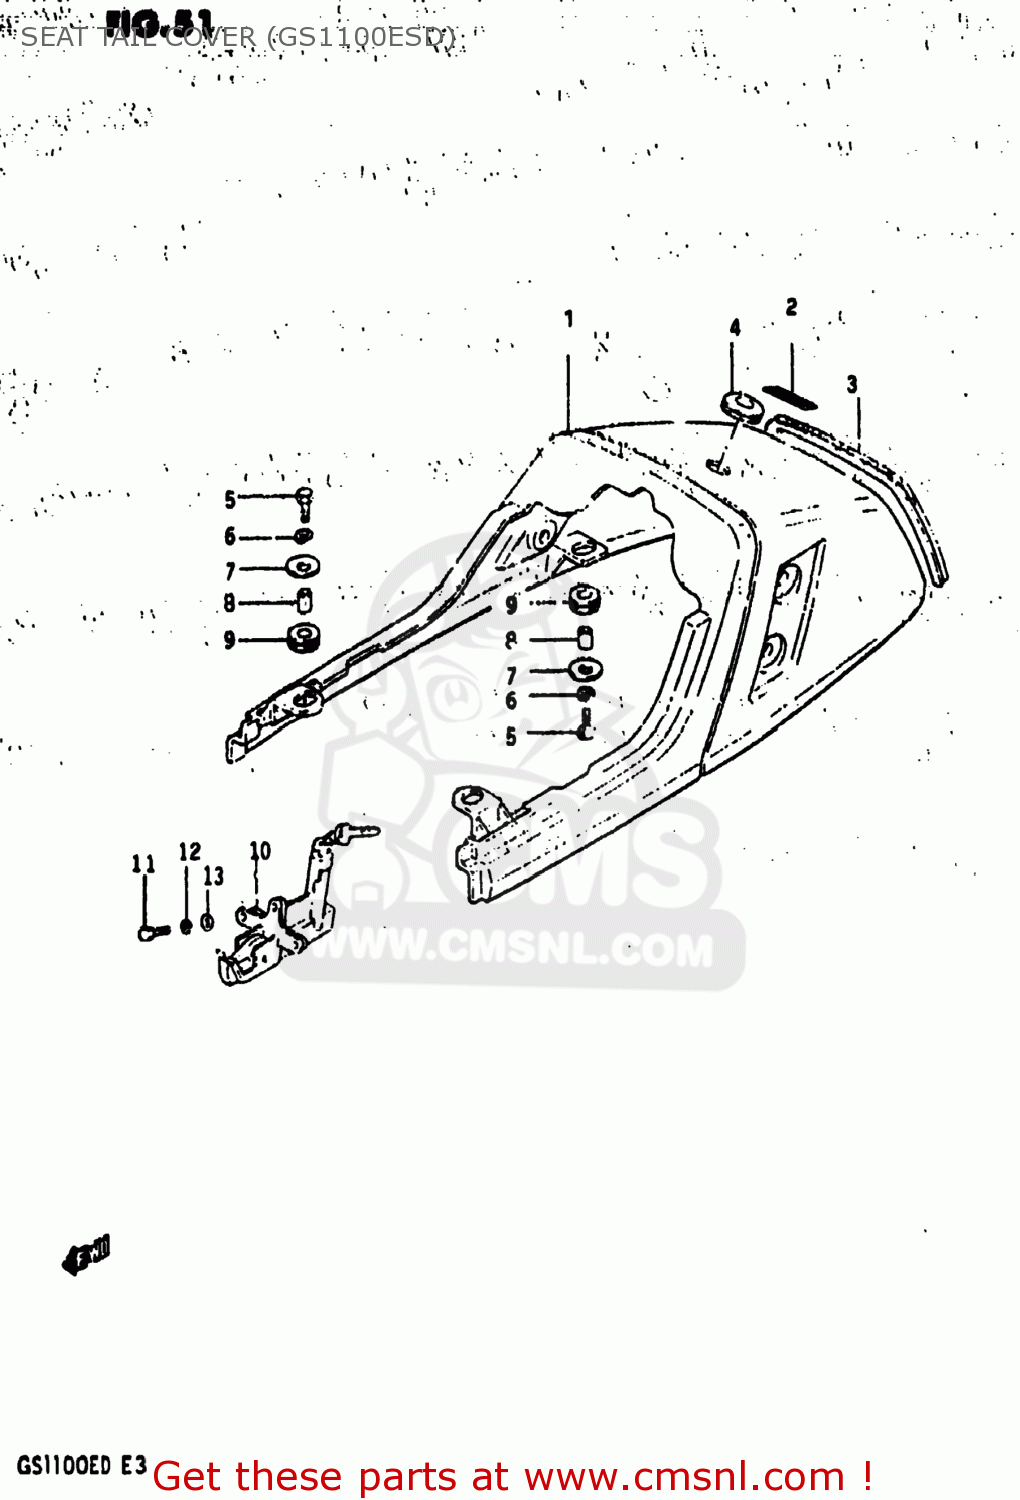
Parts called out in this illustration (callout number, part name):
1	COVER,SEAT TAIL
2	EMBLEM
3	RUBBER,BLIND,SEAT TAIL COVER
4	GROMMET,SEAT LOCK HOLE
5	BOLT
6	LOCK WASHER
7	WASHER(6,5X22X1.6)
8	SPACER(6.5X10.5X12)
9	CUSHION
10	LOCK SET,SEAT
11	BOLT
12	LOCK WASHER
13	WASHER
